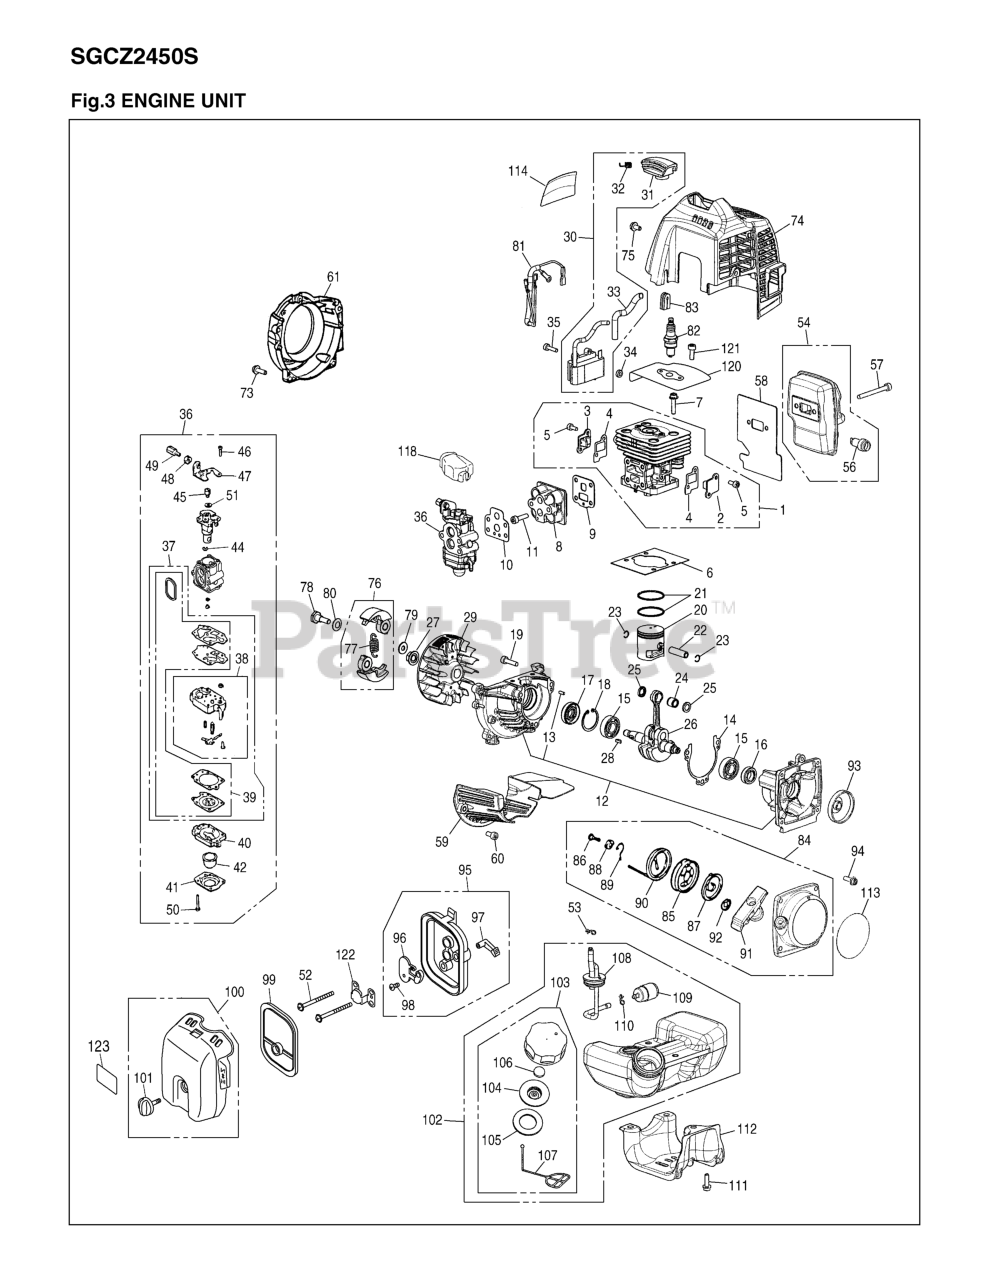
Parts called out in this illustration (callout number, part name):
1	CYLINDER COMP
2	COVER, TR-S
3	COVER, TR-F
4	GASKET, TR
5	BOLT
6	GASKET, BASE
7	BOLT
8	INSULATOR
9	GASKET
10	GASKET, CARB
11	BOLT, TORX
12	CRANKCASE COMP
13	PIN
14	GASKET, CASE
15	BEARING
16	SEAL
17	SEAL
18	RING
19	BOLT TORX
20	PISTON
21	RING
22	PIN
23	RING
24	BEARING
25	WASHER
26	CRANKSHAFT COMP
28	KEY
29	ROTOR
30	COIL ASSY
31	CAP
32	SPRING
33	TUBE
34	SPACER
35	BOLT TORX
36	CARBURETOR ASSY
37	REBUILD KIT
38	BODY ASSY
39	GASKET KIT
40	BODY
41	COVER
42	PUMP
44	RING
45	SWIVEL
46	SCREW
48	NUT
49	SCREW
50	SCREW
51	WASHER
52	BOLT
53	CLIP
54	MUFFLER ASSY
56	ARRESTER
57	BOLT
58	GASKET, MUFF
59	PLATE
60	BOLT
61	COVER, FAN
73	BOLT
74	COVER, ENGINE
75	BOLT (RPLS. T4950-51011)
76	SHOE COMP
77	SPRING
78	BOLT
79	WASHER
80	WASHER
81	CORD COMP.
82	SPARK PLUG
83	GROMMET
84	RECOIL ASSY
85	REEL
86	SCREW
87	SPRING
88	COLLAR
89	ARM
90	ROPE
91	KNOB
92	PLATE
93	PULLEY
94	BOLT, TORX
95	CLEANER BODY ASSY
96	PLATE, CHOKE
97	LEVER
98	SCREW
99	ELEMENT
100	CLEANER COVER ASSY
101	CLEANER KNOB
102	TANK ASSY
103	CAP ASSY
104	HOLDER (REPLACES -85230)
105	PACKING
106	FILTER
107	STOPPER
108	PIPE COMP
109	FUEL FILTER (BLK SLEEVE)
110	CLIP
111	BOLT
112	GUARD, TANK
113	LABEL, RECOIL
114	LABEL, EMISSION
118	COVER
120	PLATE
121	BOLT
